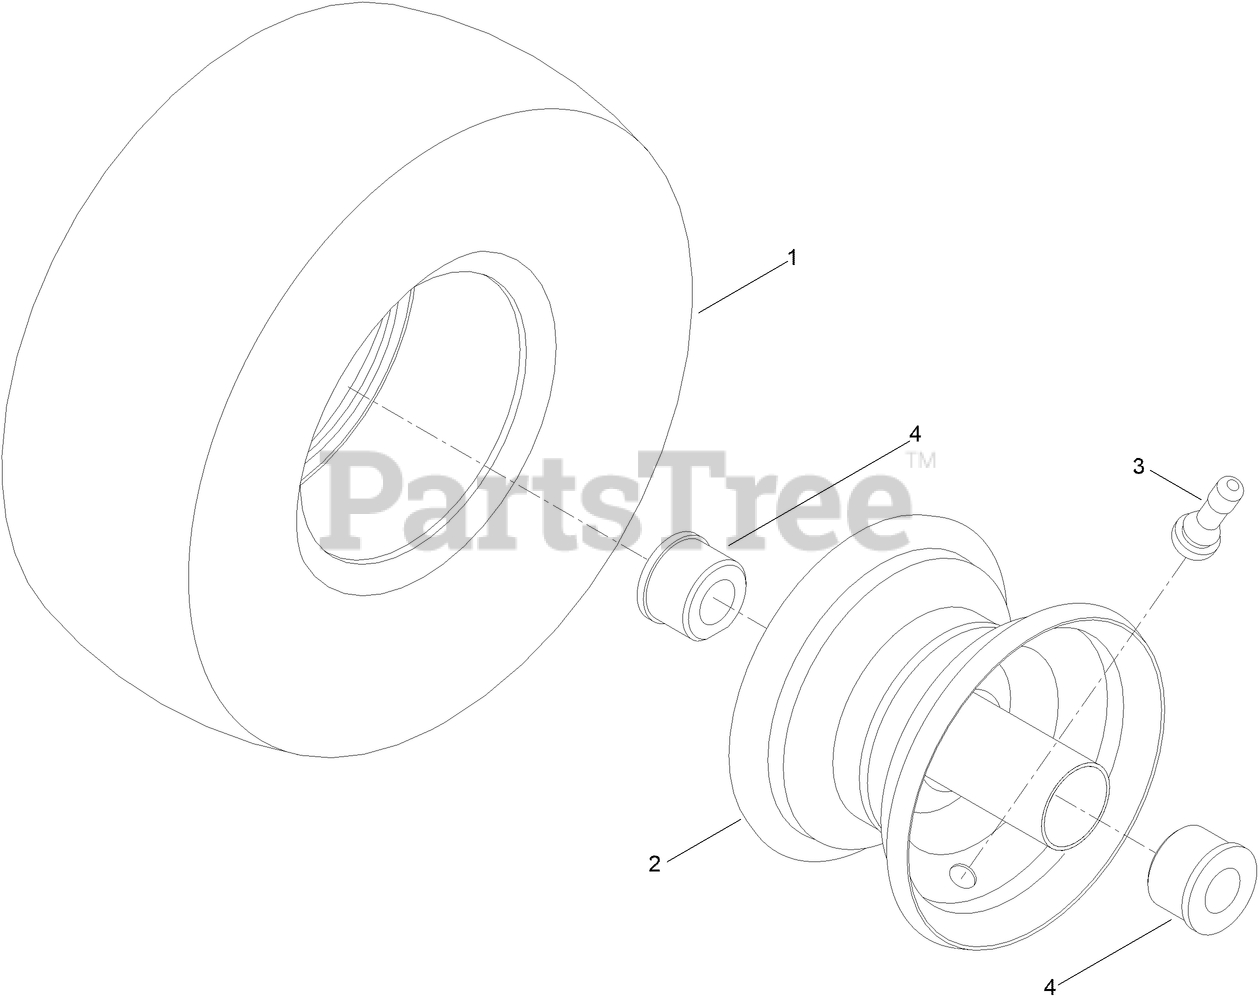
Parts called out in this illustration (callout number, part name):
1	TIRE 12X6-5
2	WHEEL (W/ ZERK AND BUSHINGS)
4	BUSHING-FLANGE
